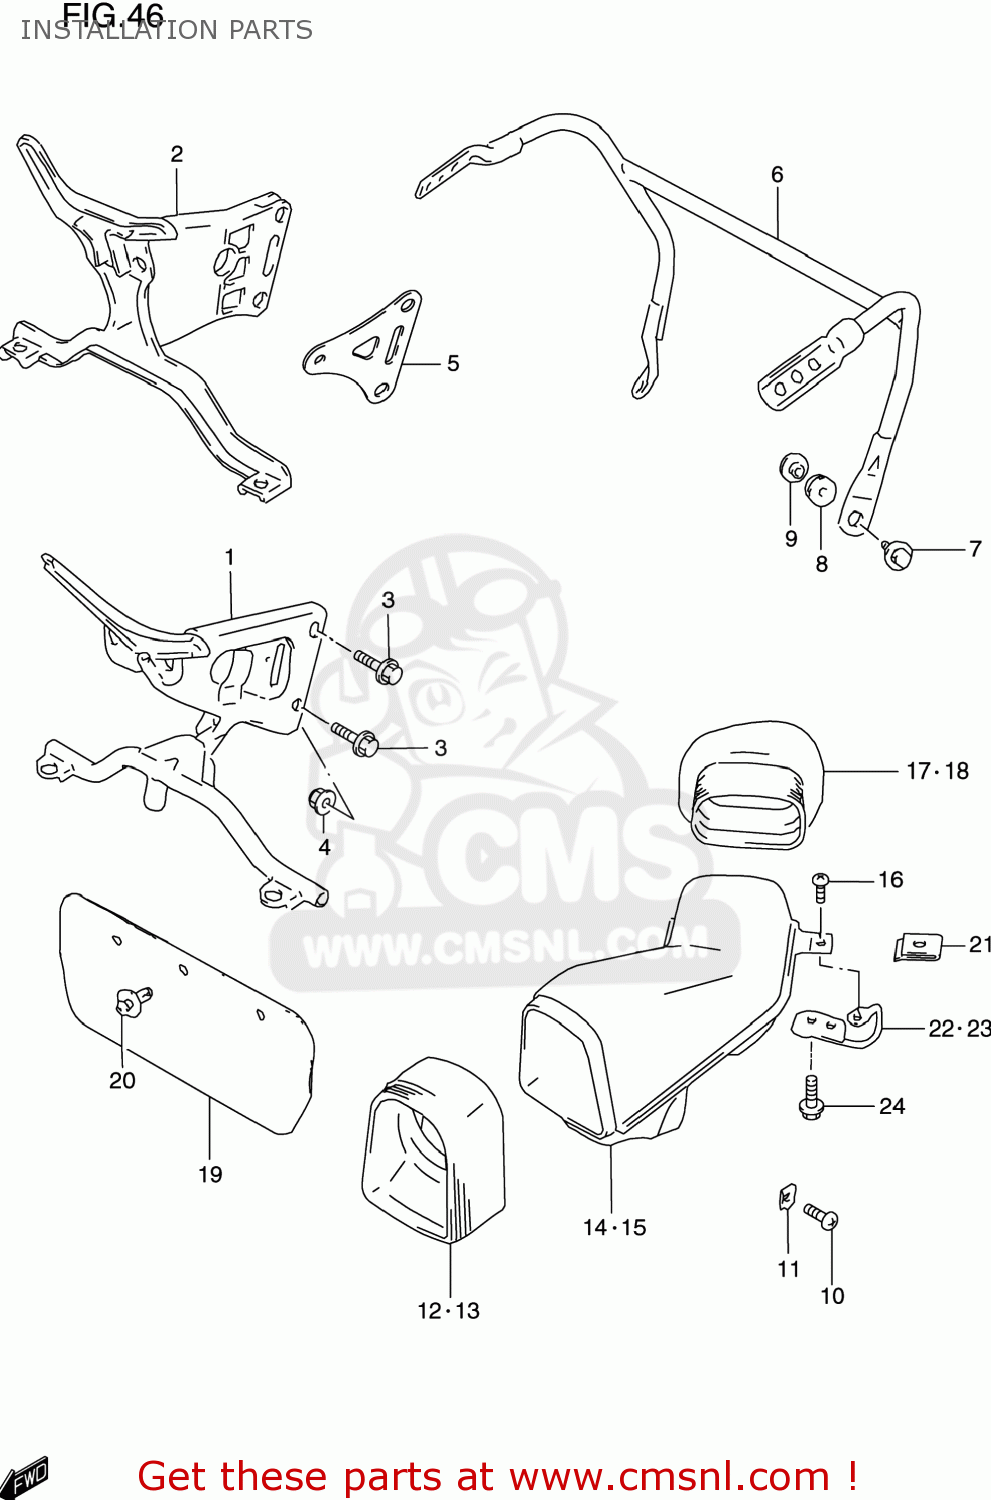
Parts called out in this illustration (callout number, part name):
1	BRACE,COWLING
2	BRACE,COWLING
3	BOLT
4	NUT
5	PLATE,COWLING BRACE
6	BRACE,RR VIEW MIRROR
7	BOLT(6X25)
8	CUSHION
9	WASHER
10	SCREW(5X16)
11	NUT,COWL
12	JOINT,AIR INTAKE,FR,R
13	JOINT,AIR INTAKE,FR,L
14	PIPE,AIR INTAKE,R
15	PIPE COMP,AIR INTAKE,LEFT
16	SCREW(5X16)
17	JOINT,AIR INTAKE,RR,R
18	JOINT,AIR INTAKE,RR,L
19	PLATE,AIR GUIDE
20	CLIP
21	PLATE,UNDER COWL FITING
22	BRACE,AIR INTAKE PIPE,R
23	BRACE,AIR INTAKE PIPE,L
24	BOLT
